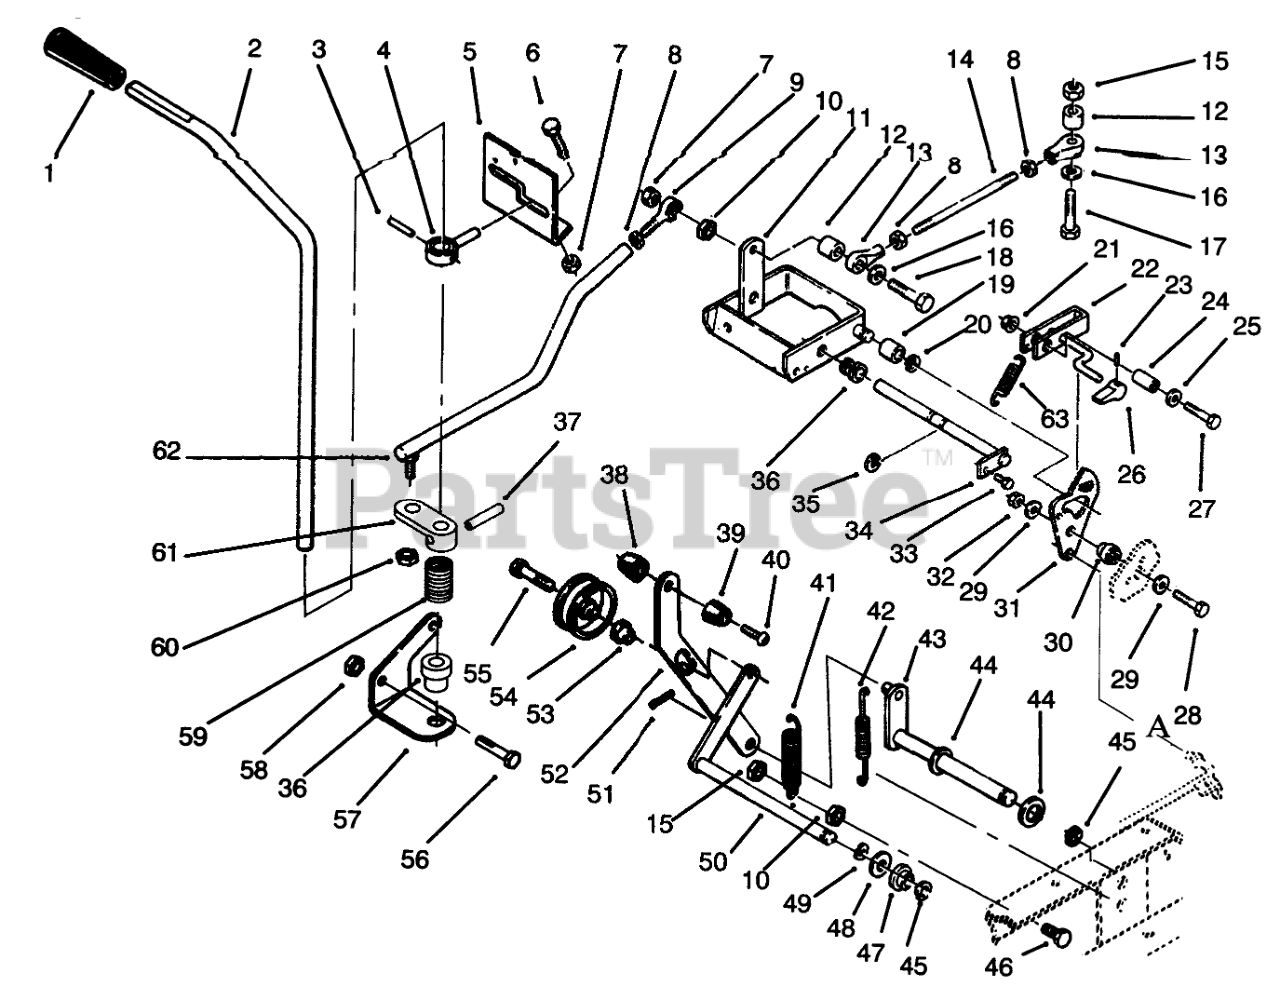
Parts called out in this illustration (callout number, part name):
1	Knob-Motion Control
2	ROD-MOTION CONTROL
3	SPIROL PIN 7/32X7/8
4	GUIDE-CONTROL
5	Bracket-Control
6	SCREW-HH
7	NUT-LOCK, NI
8	NUT-JAM
9	ROD END, 1/4-28
10	NUT-HEX
11	Cam Comtrol
12	Spacer
13	ASSY ROD END
14	ROD-CONTROL
15	NUT-LOCK
16	WASHER-FLAT
17	SCREW-HH
18	HHCS 1/4X2.25 FULL T
19	BEARING-CAM RETURN
20	RING-RETAINING, EXTERNAL
21	LOCKNUT-FLANGE
22	Lever-Parking Brake
23	PIN-SPIROL 3/32X5/8
24	SPACER
25	WASHER-SPACER
26	KNOB-PARKING BRAKE
27	SCREW-HH
28	SCREW-HH
29	WASHER-FLAT
30	Spacer
31	Cam Plate
32	NUT-LOCK, NI
33	Bolt
34	ASSY-ROD CAM PIVOT
35	RING-RETAINING, EXTERNAL
36	NYLINER BUSHING
37	PIN-SPECIAL
38	KNOB
39	KNOB
40	Screw
41	SPRING-EXTENSION
42	SPRING-EXTENSION
43	ASSY-BRAKE LEVER
44	WASHER
45	E Ring
46	SCREW-HH
47	BUSHING-FLANGED
48	SHIM-WASHER
49	CURVED-SPRING WASHER
50	WLDMT-IDLER ARM
51	PIN-COTTER
52	Handle
52	ASSY-ARM/ROD WA
53	SPACER-BRAKE LINK
54	PULLEY-IDLER
55	BOLT-SPECIAL HEX
56	SCREW-HH
57	Bracket-Control
58	NUT-LOCK, NI
59	SPRING-COMPRESSION
60	NUT-LOCK
61	ARM-CONTROL
62	ASSY-ROD & BALL JOINT
63	EXTENSION-SPRING
